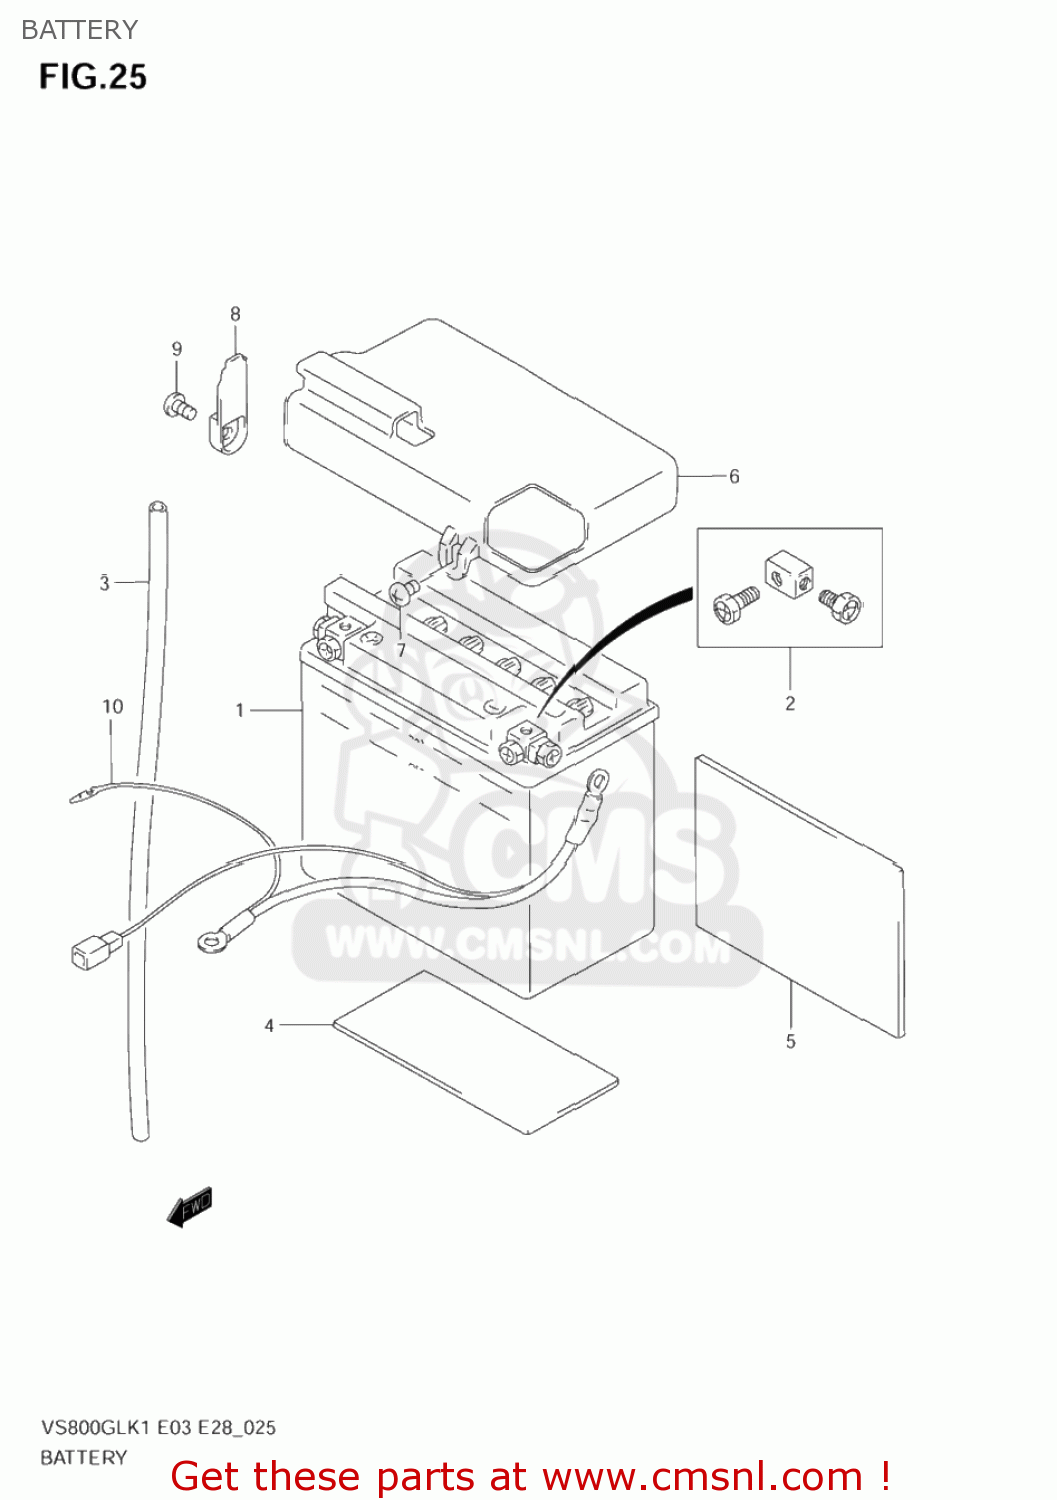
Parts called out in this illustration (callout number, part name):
1	BATTERY ASSY (12V)
2	BOLT SET,BATTERY TERMINAL
3	HOSE,BATTERY EXHAUST(L:780)
4	PROTECTOR(170X95X3.0)
5	PROTECTOR(80X80X2)
6	COVER,BATTERY UPR
7	SCREW
8	COVER,BATTERY TERMINAL
9	SCREW
10	WIRE,BATTERY MINUS LEAD
